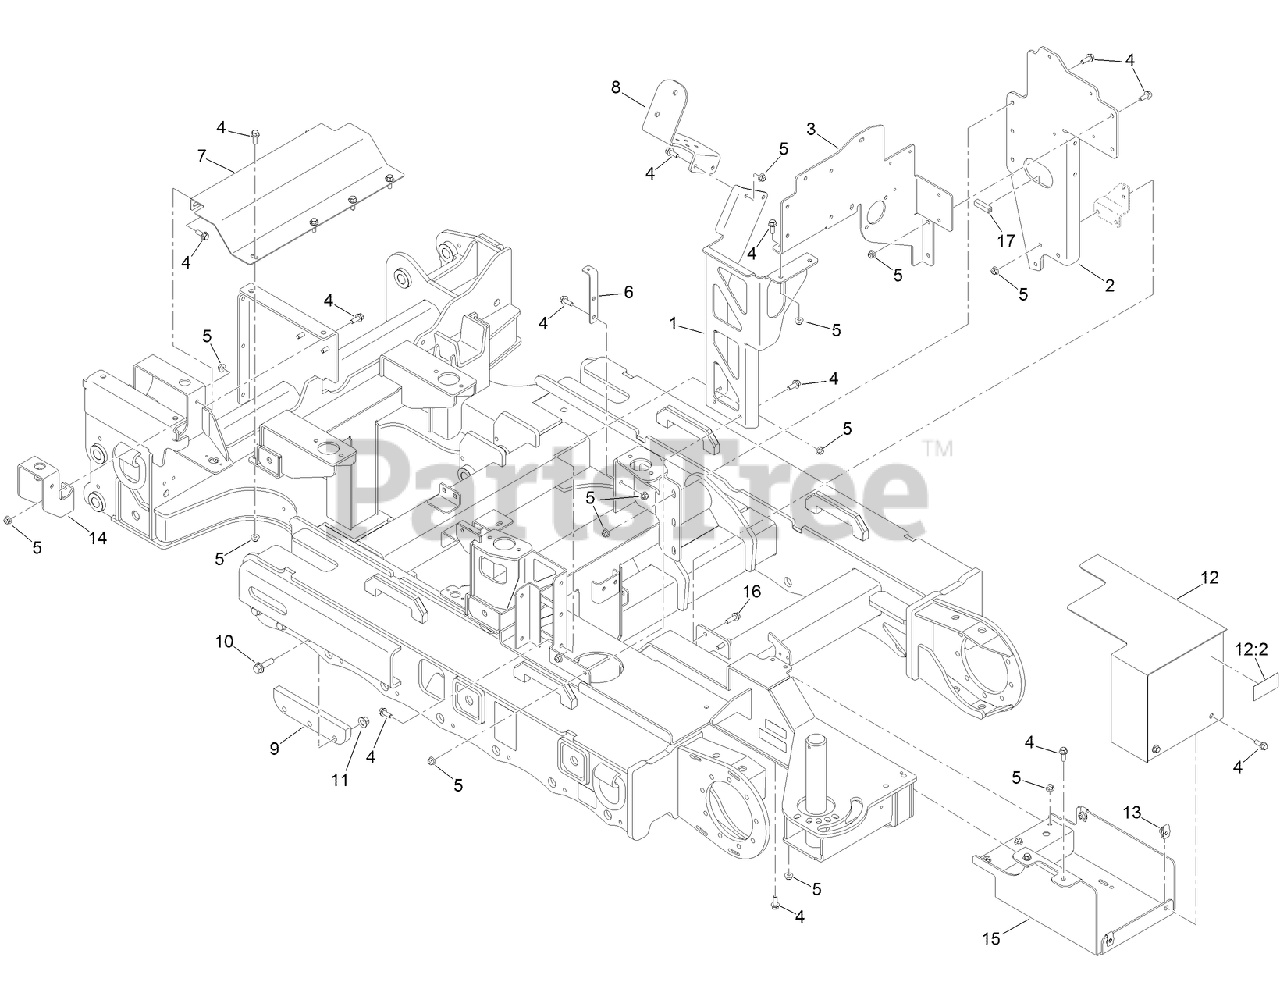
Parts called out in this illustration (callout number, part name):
2	PLATE-MOUNT, ECU
3	PANEL-ELECTRICAL, FRONT
4	SCREW-HHF
5	NUT-HF, NI
6	BRACKET-CLIP, HARNESS
7	PLATE-RECIRCULATION
8	PLATE-MOUNT, TOP
9	PLATE-TENSIONER, SLIDER
10	SCREW-HHF
11	NUT-LOCK
12	COVER-BATTERY
12:2	DECAL-WARNING, BATTERY
13	NUT-TINNERMAN
14	GUSSET-TRACK
15	COVER-BATTERY, LOWER
16	SCREW-HHF
